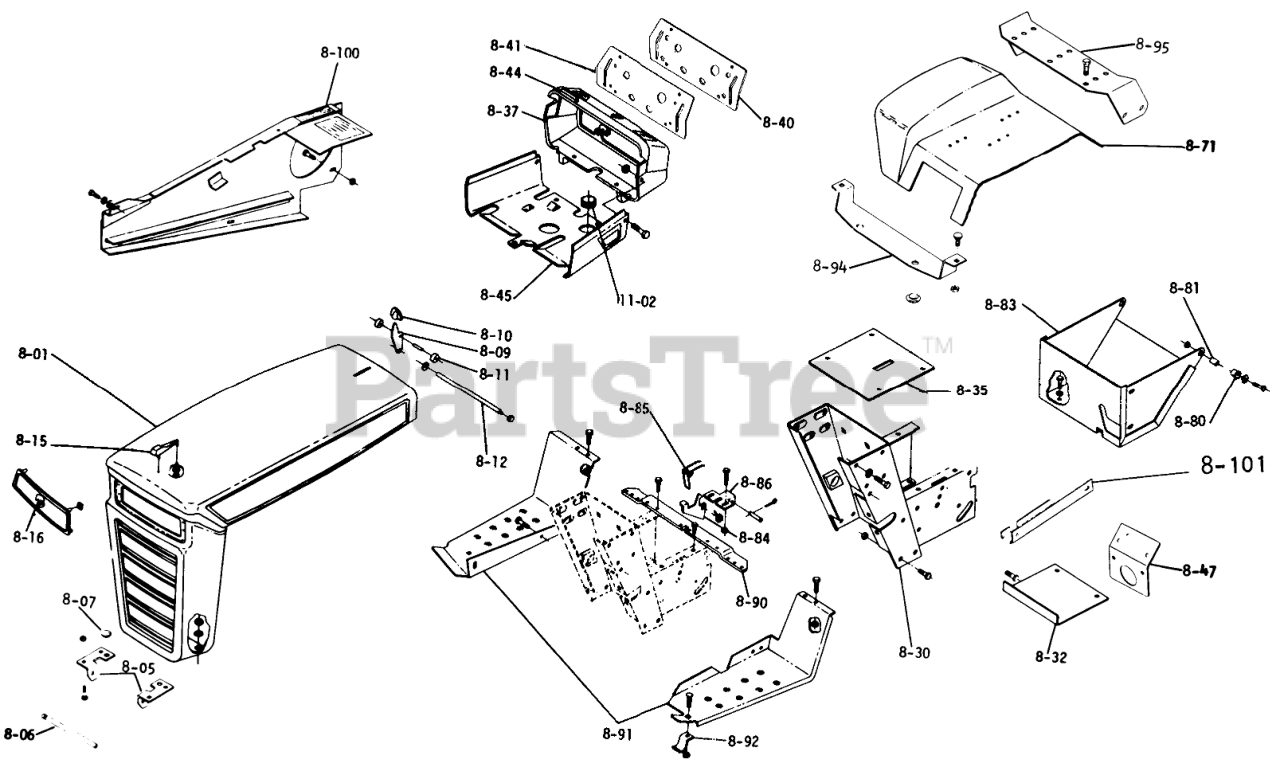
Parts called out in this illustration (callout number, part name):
8-01	Hood
8-05	GRILL PIVOT BRKT
8-05	Bracket-Grille-L.H.
8-05	Bracket-Grille-R.H.
8-05	BRKT.GRILLE PIVOT LH
8-06	GRILL PIVOT ROD
8-09	LEVER HOOD LATCH
8-10	KNOB
8-11	Roller
8-12	Rod Latch
8-15	Hood Ornament
8-16	ESCUTCHEON PLATE
8-30	Hoodstand Ass-y.
8-32	Cover-Dust
8-35	Cover Plate
8-37	Housing
8-40	Dash Panel
8-41	BACK UP PLATE
8-44	Tape
8-45	Support-Tank
8-47	Instrument Backet
8-71	Fender
8-80	BUSHING-FLANGED
8-81	SPACER
8-83	Tool Box
8-84	Fender Latch
8-85	Spring
8-86	BRACKET FENDER LATCH
8-90	Bracket
8-90	Bracket-Footrest
8-91	Footrest-RH
8-91	Footrest-L.H.
8-92	BRACKET
8-94	Fender Bracket
8-95	Bracket Fender Hinge
8-100	Belt Guard
8-101	Channel
